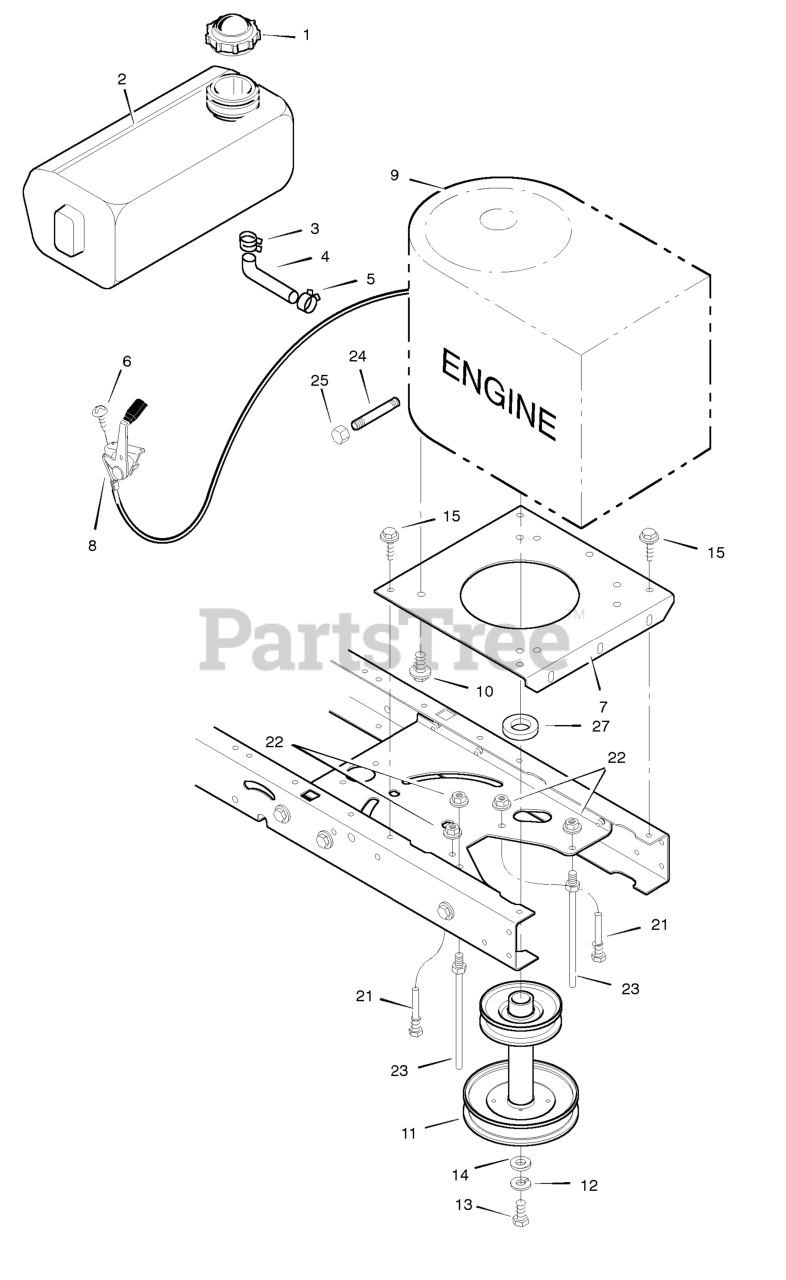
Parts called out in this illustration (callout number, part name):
1	Fuel Cap
2	Fuel Tank
3	Hose Clamp
4	Fuel Line
5	Hose Clamp
7	Plate, Engine
8	Throttle Control
9	Engine *
10	Bolt, Engine Mount
11	Stack Pulley Assembly
12	Lockwasher
13	Bolt, Hex
21	Guide, Belt
22	Nut, Flange
23	Guide, Belt
24	Pipe, Oil Drain
25	Cap, Oil Drain
